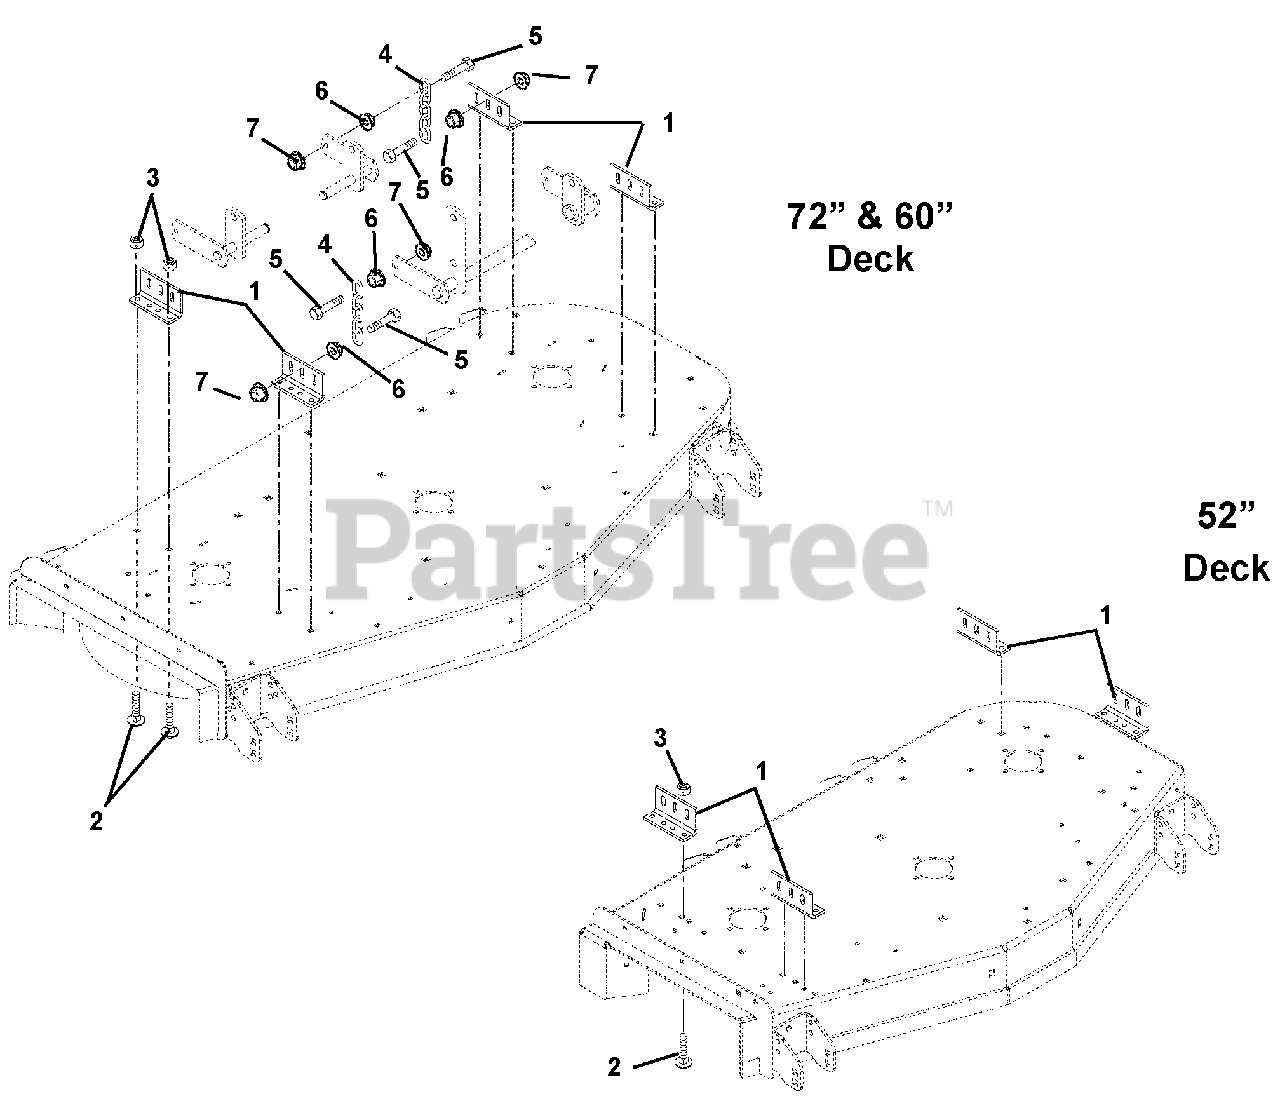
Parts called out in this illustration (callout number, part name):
1	Bracket, Mower Mounting
2	Bolt-Round Head Square Neck .38-16 x 1.00 Grade 2
3	Nut-Locking-Top-Flange .38-16
4	Chain, Link
5	Bolt-Hex M12-1.75 x 55 Grade 5
6	Nut, Spin Lock Flange M12-1.75
7	Nut-Locking-Top-Flange M12-1.75
